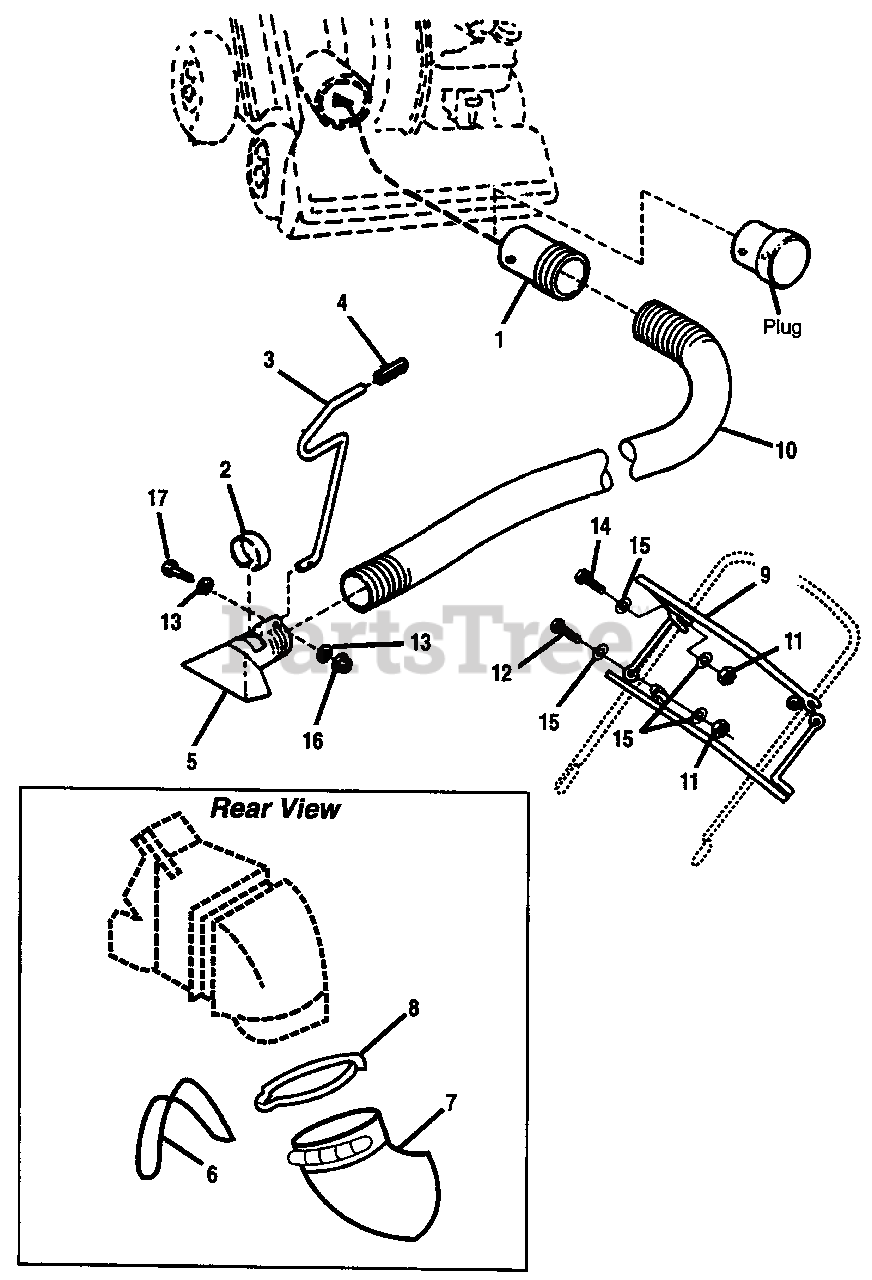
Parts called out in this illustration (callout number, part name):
2	RING, Plastic
3	HANDLE
6	STRAP, Rubber
7	TUBE, Deflector
9	HOSE CARRIER, Half
10	HOSE, 4" Diameter x 15' Long
11	NUT, Esna, 5/26-18
12	CAPSCREW, 5/16-18 x 1-1/2
13	WASHER
14	CAPSCREW, 5/16-18 x 2-1/2
16	NUT, Whizlock, 1/4-20
17	SCREW, 14-20 x 1-1/2
